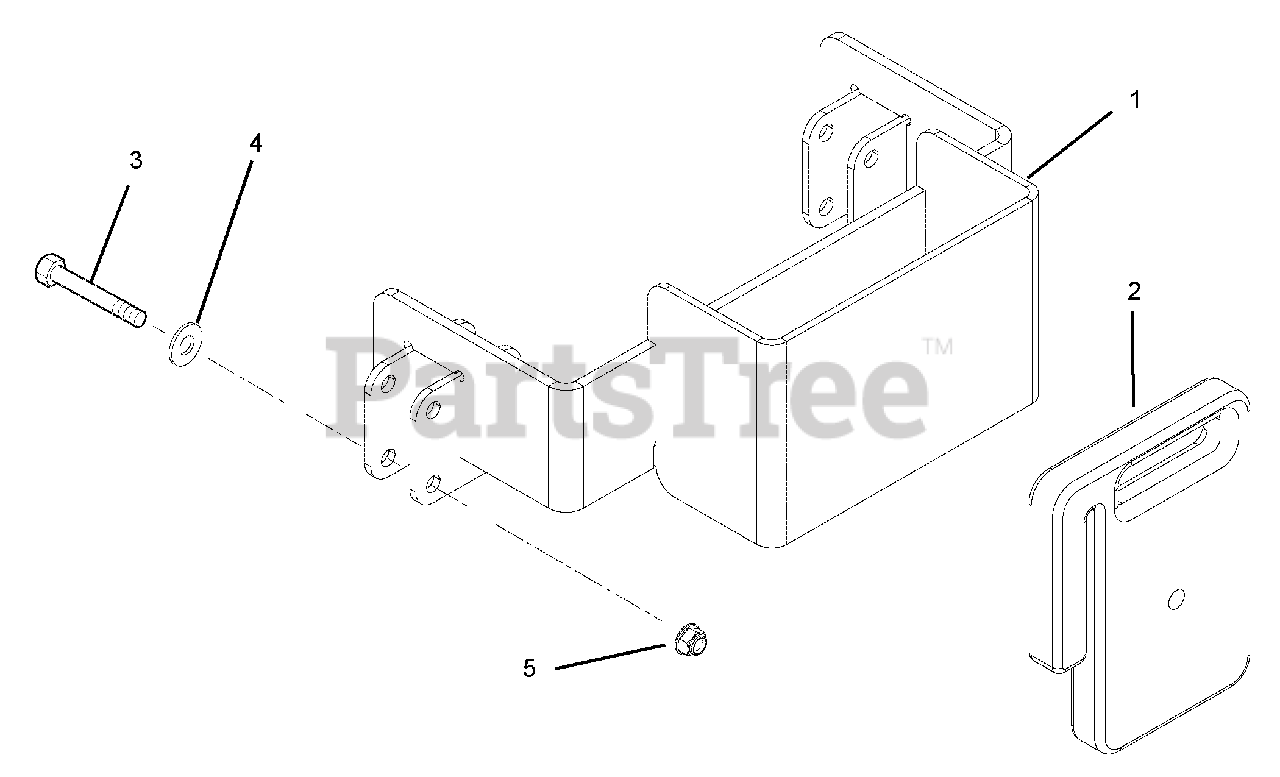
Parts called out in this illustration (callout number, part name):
1	Bracket, Bagger Weight
3	Bolt .38-16 x 2.25
4	Washer .408 x 1.0 x .188
5	Nut, Nuloc Flange
